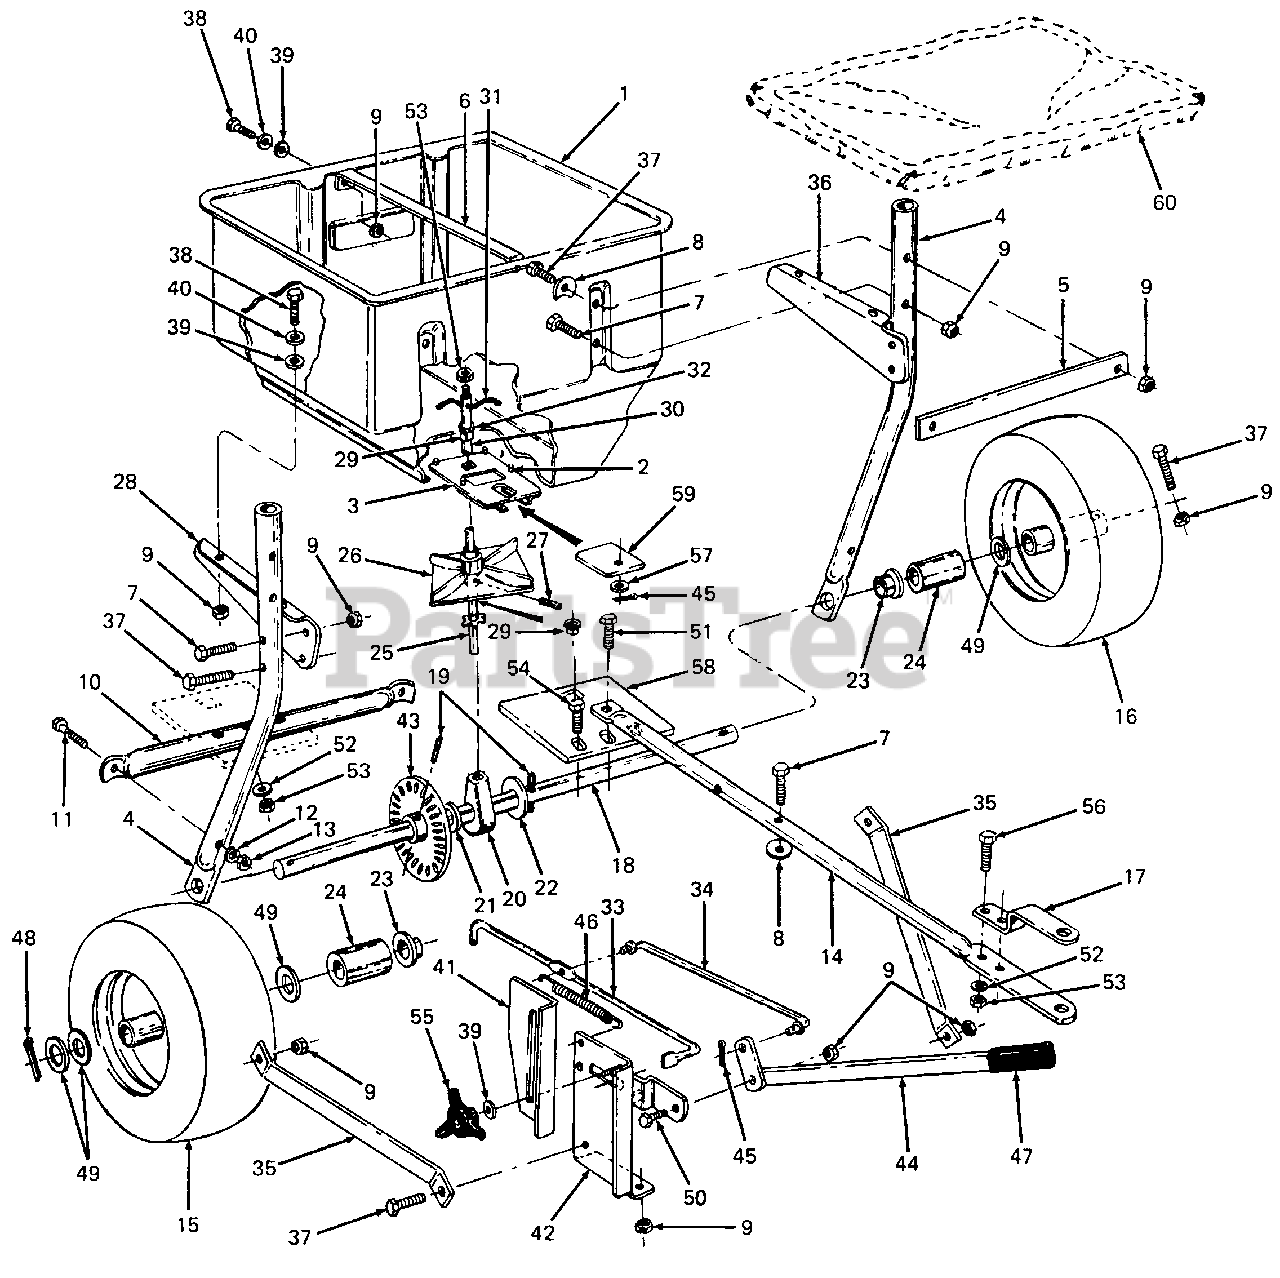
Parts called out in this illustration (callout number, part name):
3	Closure Assy, Guide
4	Support Tube, Hopper/Axle
5	Strap, Tube
6	Strap, Hopper
7	Screw, Hex Cap, 1/4-20 X 1.5 Lg GR 5
8	Washer, Bowed, 1/4 ID
9	Nut, Hex Patch Lock, 1/4-20
10	Tube, Crossover
11	Screw, Hex Cap, 5/16-18 X 1.75 Lg
12	Washer, Lock, 5/16
13	Nut, Hex Center Lock, 5/16-18
14	Tube, Hitch
15	Wheel Assy, w/Bearing RH, 14 X 4
16	Wheel Assy, Drive LH, 14 X 4
17	Bracket, Hitch
18	Shaft, Axle
19	Pin, Roll, 3/16 Dia X 1.25 Lg
20	Bushing, Axle/Shaft
21	Washer, Flat, .781 X 1.59 X .06
22	Washer, Flat, .81 X 2.0 X .150
23	Bearing, Flange
25	Shaft, Sprocket
26	Plate Assy, Spreader
27	Pin, Spring, 1/8 X .62 Lg
28	Brace, Hopper RH
29	Bushing, Nylon, .375 ID
30	Sleeve, Agitator
31	Wire, Agitator
32	Nut, Push, 3/8
33	Rod, Slide Gate
34	Rod, Flow Control
35	Brace, Hitch
36	Brace, Hopper LH
37	Screw, Hex Cap, 1/4-20 X 1.75 Lg
38	Screw, Hex Cap, 1/4-20 X .75 Lg GR 5
39	Washer, Nylon
40	Washer, Flat, .281 X .73 X .063
41	Metering Gage, Flow Control
42	Mounting Assy, Flow Control
43	Gear Assy
44	Arm Assy, Flow Control
45	Pin, Cotter, 3/32 Dia X .75 Lg
46	Spring, Extension
47	Grip, Flow Control Arm
48	Pin, Cotter, 1/8 Dia X 1.5 Lg
49	Washer, Flat, .781 X 1.59 X .065
50	Screw, Hex Cap, 1/4-20 X 1/2 Lg GR 5
51	Screw, Hex Cap, 3/8-16 X 2.0 Lg GR 5
52	Washer, Lock, 3/8
53	Nut, Hex Center Lock, 3/8-16
54	Screw, Hex Cap, 3/8-16 X 1-3/4 Lg GR 5
55	Knob, Plastic, 1/4-20
56	Screw, Hex Cap, 3/8-16 X 1.25 Lg GR 5
57	Washer, Flat, .344 X .62 X .063
58	Support, Shaft
59	Plate, Closure
60	Cover, Vinyl Hopper (Optional)
